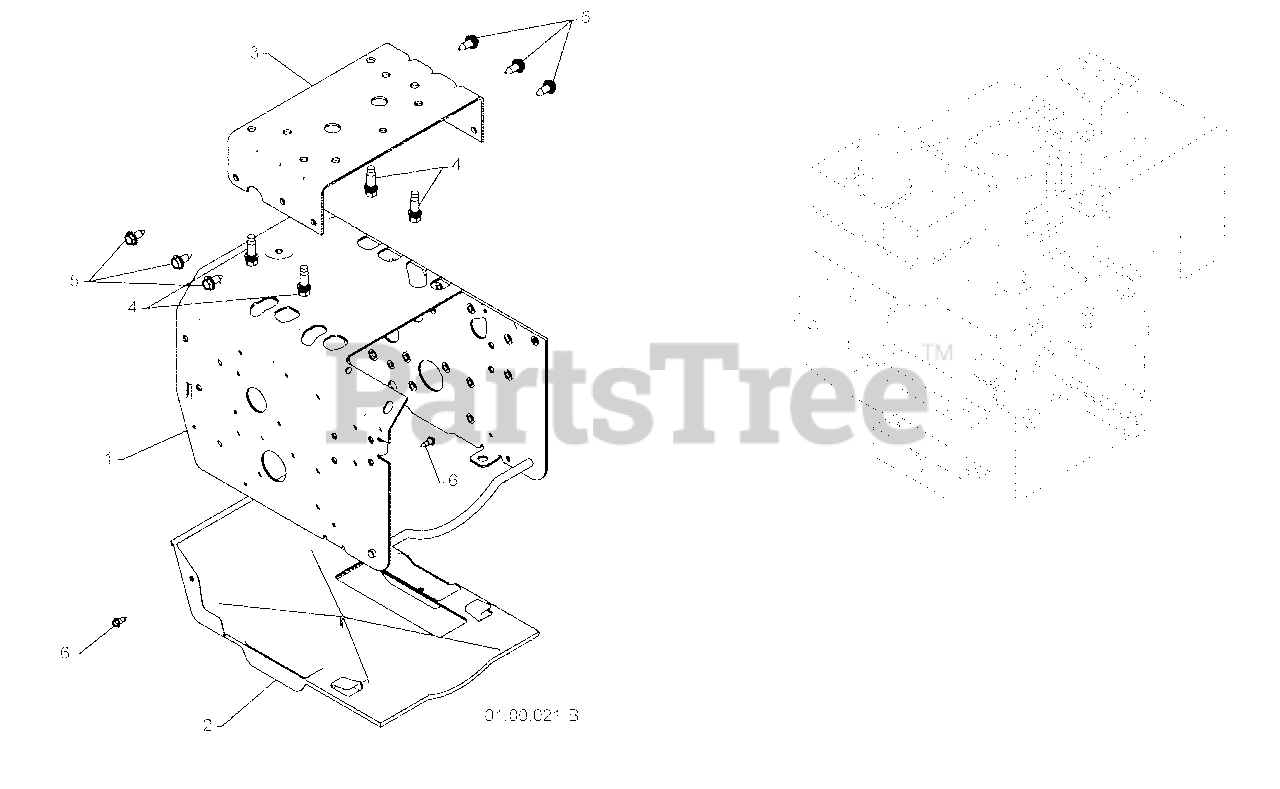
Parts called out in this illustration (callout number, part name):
2	BOTTOM PAN
3	ENGINE MOUNT PLATE
4	BOLT 3/8-16
5	SCREW 5/16-18 X .750
6	SCREW 10-24 X .625
